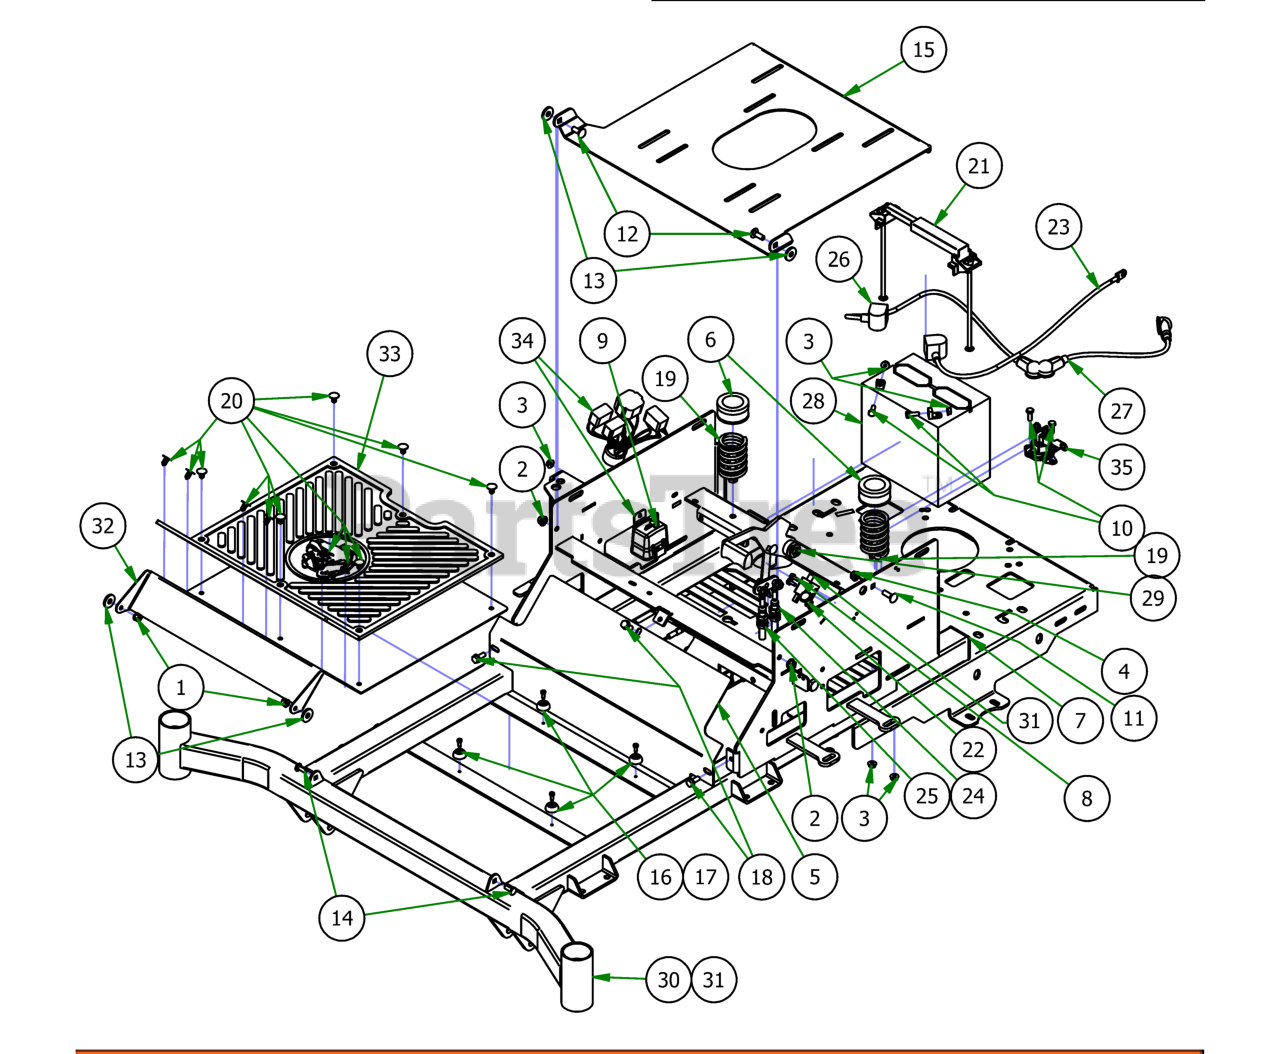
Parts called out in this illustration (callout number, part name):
1	1/4-20 Nylon Insert flange Nut
2	5/16" Nylon Flange Nut
3	1/4-20 Hex Flange Nuts Zinc w/Serrations
4	5/16" Flange Nut
5	2017 ZT Cooler Cover
6	Seat Spring Cap Cover
7	2x2 Square Plug
8	12-24x 1/2 HWH Bolt
9	1/4" x 1/2" BS C/S 18-8 SS
10	1/4" x 3/4" Hex Bolt
11	5/16" x 1" Carriage Bolt
12	5/16" x 7/8" Carriage Bolt
13	.360 ID Plastic Washer
14	1/4" x 3/4" Carriage Bolt
15	2017 MZ Seat Plate
16	Button Bumper
17	#10 x 1/2" Self Tapping Screw
18	5/16 x 3/4 washer head type F screw
19	Seat Spring Assembly
20	5/8" Christmas Tree Fastener
21	Hold Down Assembly
23	Ground Cable
24	2021 Load Balanced Brake Cable 1
25	2021 Load Balanced Brake Cable 2
26	24" Red Battery Cable
27	12" Red Battery Cable
29	2021 Load Balanced Brake Handle Assembly
30	2017 MZ/ZT 54"-60" Frame
31	Safety Switch
32	MZ/ZT 2017 Floorboard
33	2017 MZ/ZT Floor Mat
34	Wiring Harness
